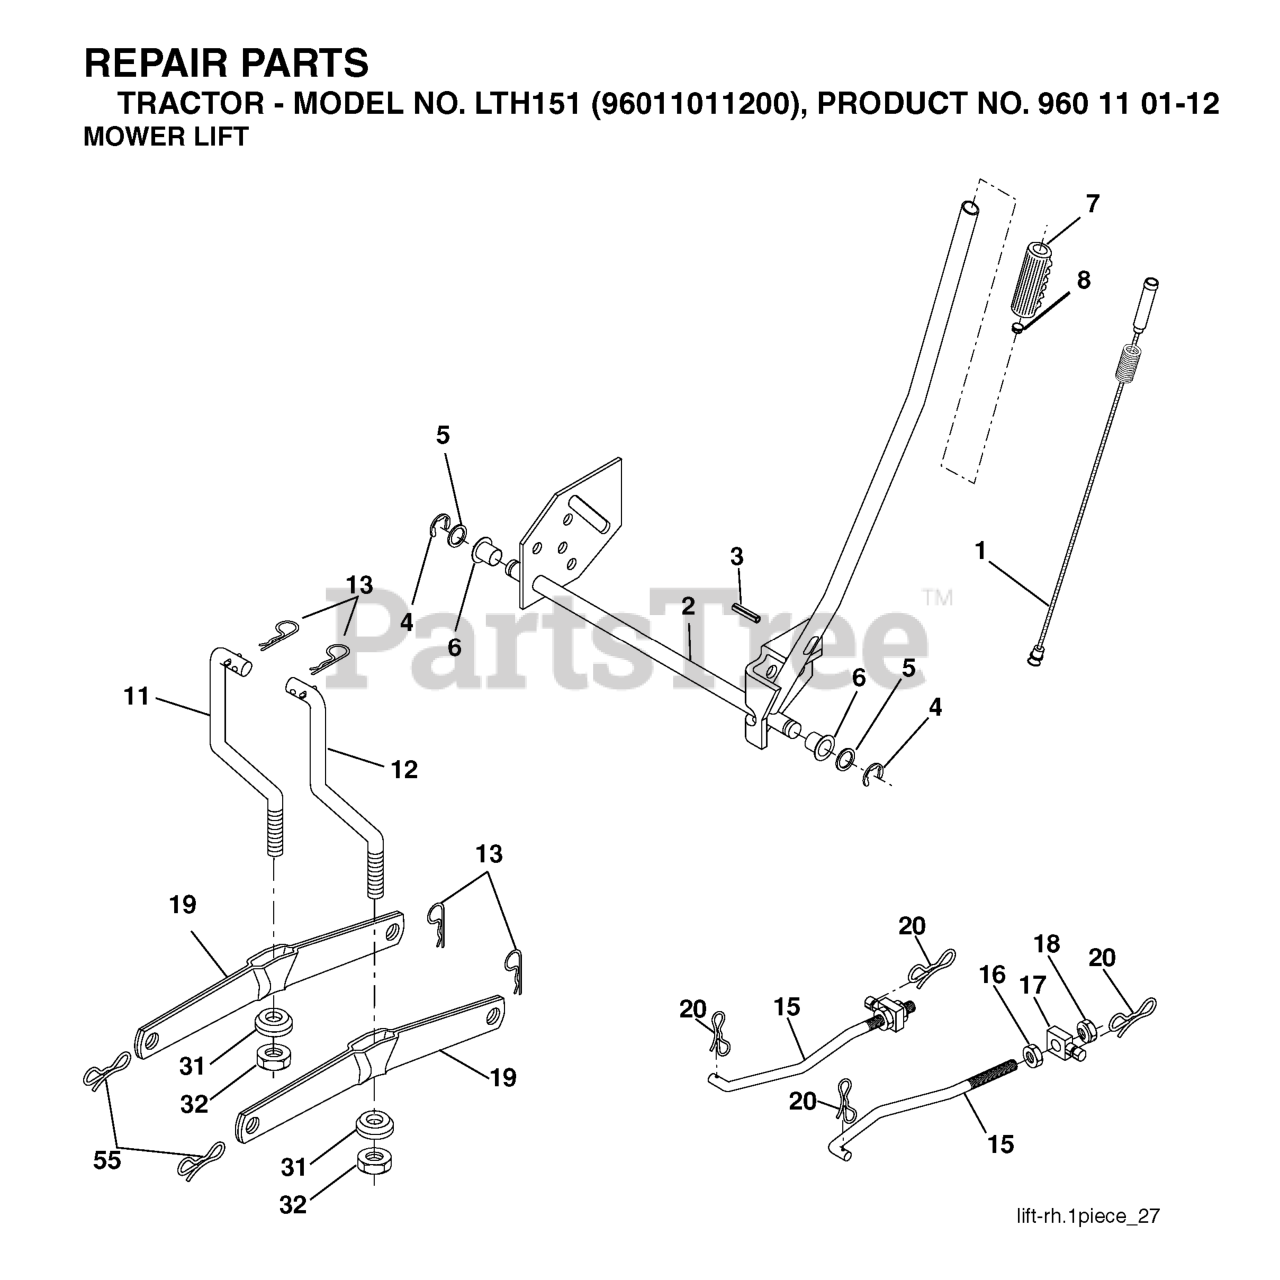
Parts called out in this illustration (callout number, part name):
1	WIRE ASM INNER W/ PLUNGER LT
2	SHAFT ASM R HANDLE
3	PIN GROOVE.
4	RETAINING RING LT
6	BEARING.NYLON
8	PLUNGER BUT KIT
11	LINK LIFT LH
12	LINK LIFT RH
13	RETAINER-SPRNG RB
15	LINK.SUSPENSION.FRONT
16	NUT.HEX.JAM.1/2-13
18	NUT.LK.W/WSH.1/2.
19	ARM.REAR.SUSPENSION
20	PIN.COTTER.7/16.BOW TI.
31	BEARING.PIVOT.LIFT
32	NUT CROWNLOCK 3/8-24
55	PIN.COTTER.5/16.BOW TI
